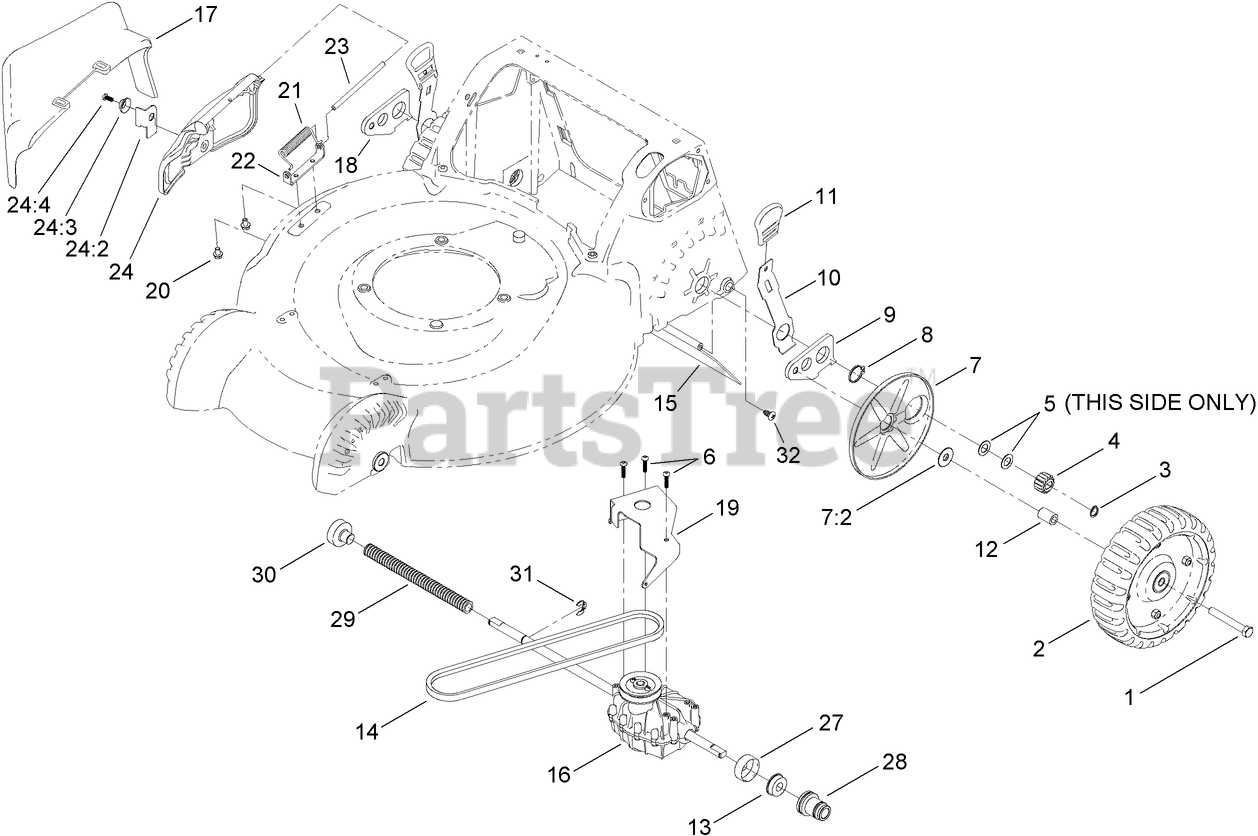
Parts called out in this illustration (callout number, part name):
1	SCREW-HH
2	8-INCH WHEEL ASM
3	RING-RETAINING
4	GEAR-PINION, 15T
5	WASHER-PLAIN
6	SCREW-PLASTITE
7	WHEEL COVER ASM
7:2	WASHER-STEPPED
8	RING-RETAINING
9	ARM-REAR PIVOT, LH
10	ARM-SPRING, REAR
11	KNOB-HOC
12	SPACER
13	BEARING-BALL
14	V-BELT
15	SHIELD-TRAILING
16	TRANSMISSION
17	CHUTE-DISCHARGE, SIDE
18	ARM-REAR PIVOT, RH
19	BRACKET-TRANSMISSION
20	SCREW-HWH
21	SPRING-TORSION
22	BRACKET-COVER
23	ROD-COVER
24	DISCHARGE DOOR ASM
24:2	LATCH-DOOR
24:3	CAP-DOOR
24:4	SCREW-PLASTITE
27	Cover-Bearing
28	RETAINER-BEARING
29	Cover-Shaft, Drive
30	CAP-BEARING
31	RING-CLIP, LOCKING
32	SCREW-PTH
